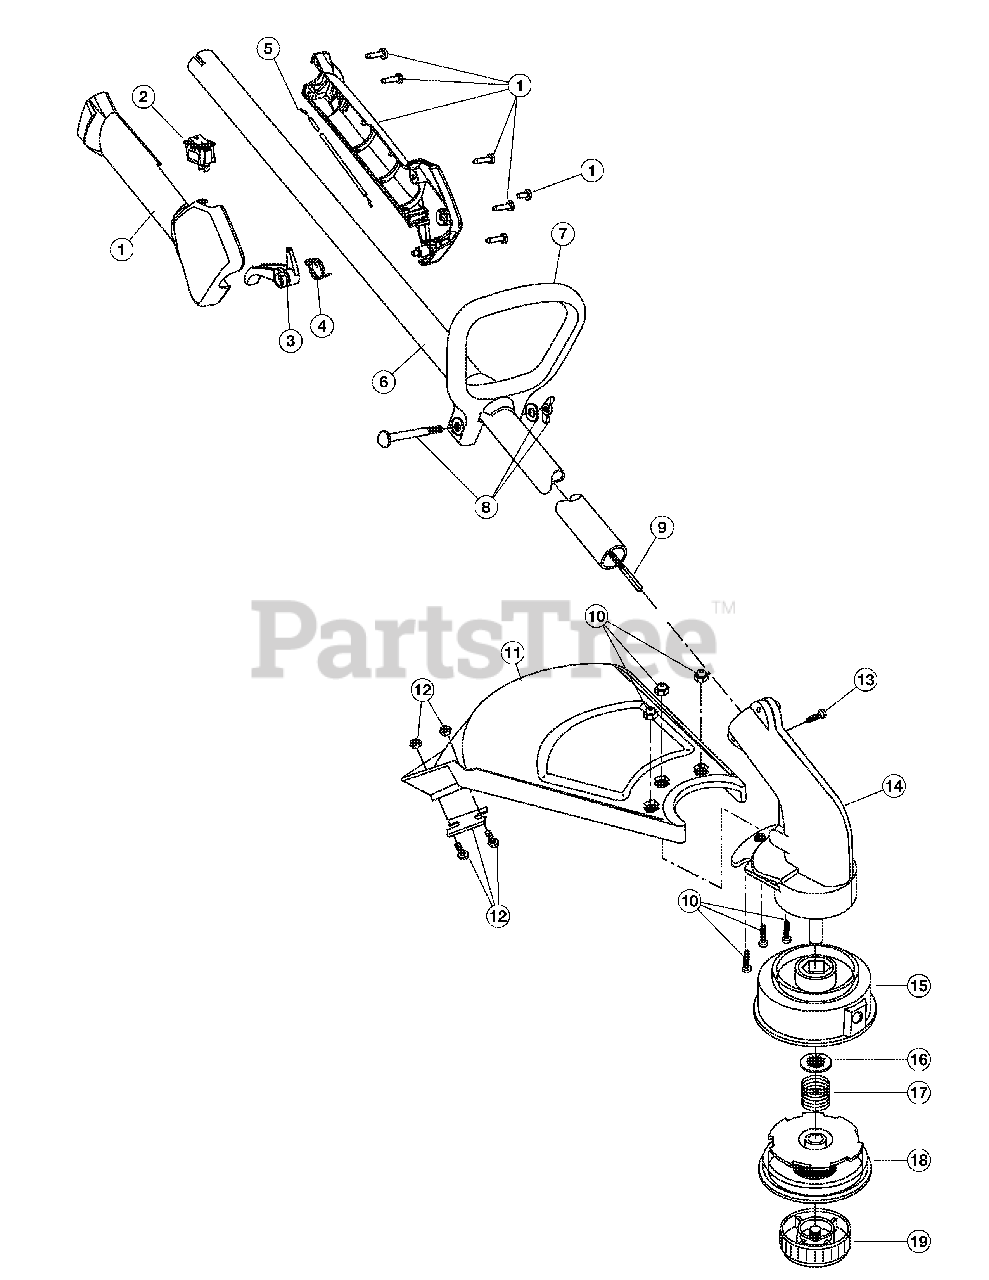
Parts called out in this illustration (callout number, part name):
1	Throttle Housing Assembly (Incl. Ref No. 2-4)
3	Throttle Trigger
4	Throttle Trigger Spring
5	Throttle Cable
6	Drive Shaft Housing Assembly
7	D-Handle (Incl. Ref No. 8)
8	D-Handle Hardware Assembly
9	Flexible Drive Shaft
10	Guard Mounting Screw Assembly
11	Guard Assembly (Incl. Ref No. 12)
12	Blade Assembly
13	Anti-Rotation Screw
14	Gearbox Assembly (Incl. Ref No. 15-19)
15	Outer Spool Assembly (Incl. Ref No. 16)
16	Retainer (10 pack)
18	Inner Reel
19	Bump Head Knob Assembly
